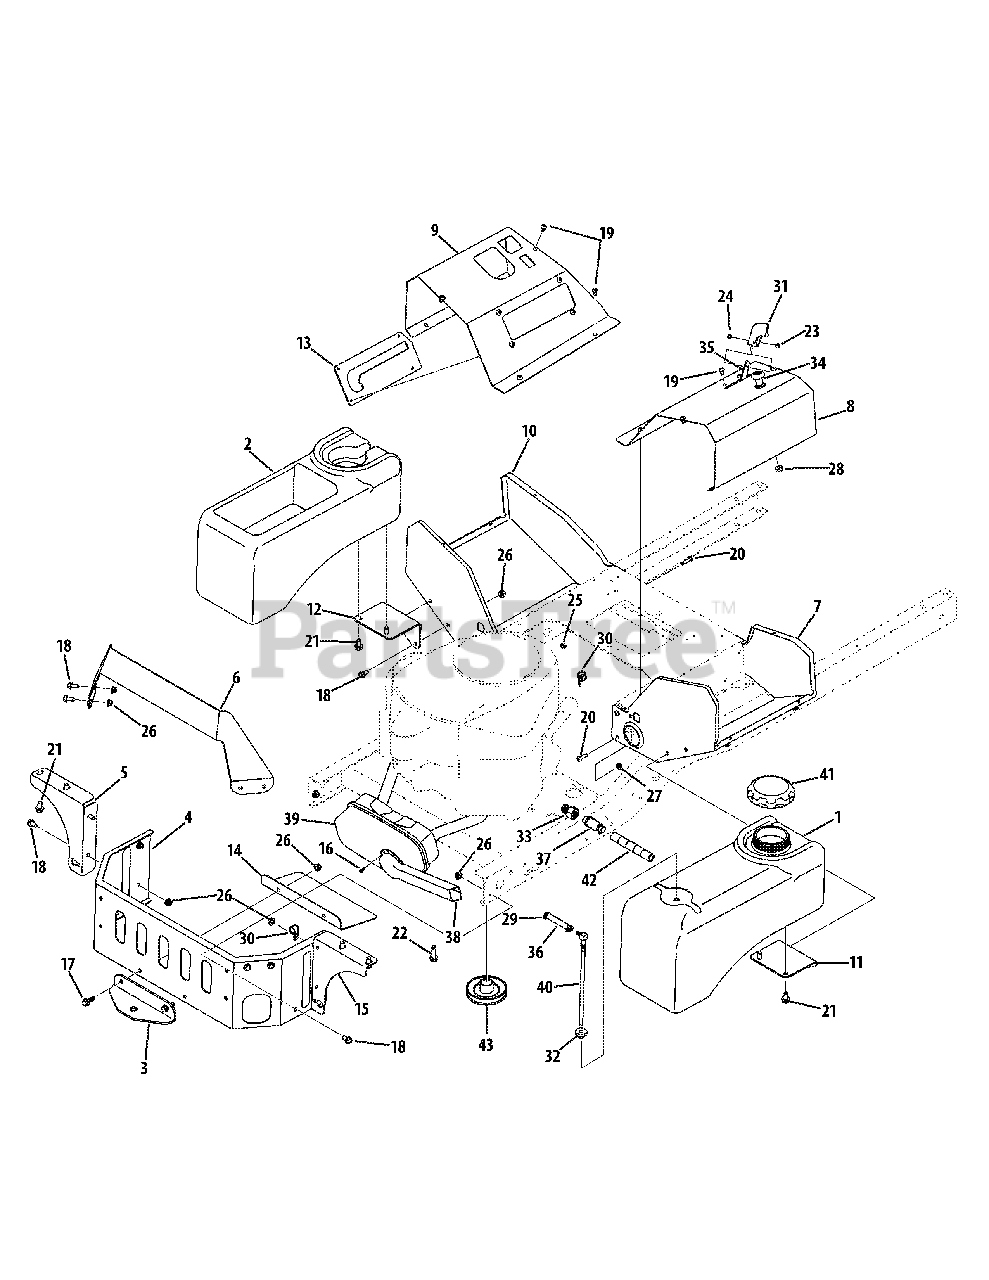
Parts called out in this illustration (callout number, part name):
1	Fuel Tank
2	Utility Bin
3	Hitch Bracket
4	Bumper Bracket
5	Tank Support Bracket
6	Upper Bumper Bracket (60" Only)
7	RH Lower Console
8	RH Upper Console
9	LH Upper Console
10	LH Lower Console
11	Right Tank Support Bracket
12	Left Tank Support Bracket
13	Parking Brake Lock Bracket
14	Muffler Mount Bracket
15	RH Fuel Tank Support Bracket
16	Hex Washer Screw, #8-18 x 0.500
17	Hex Flange, 5.16-18 x 1.0
18	Hex Washer Screw, 5.16-18 x .750
19	Screw, 1.4-20 x .5
20	Screw, 1.4-20 x 1.0
21	Hex Washer Screw, 3.8-16 x .625
22	Hex Washer Screw, 3.8-16 x 1.250
23	Machine Screw, #8-32 x0.375
24	Hex Nut, #8-32
25	Sems Nut, 1.4-20
26	Flange Lock Nut, 5.16-18
27	Flange Lock Nut, 1.4-20
28	Flange Lock Nut, 3.8-16
29	Hose Clamp, .490
30	Clamp, 9.16
31	Throttle Knob
32	Fuel Tank Bushing
33	Hex Fitting, 10 x M20
34	Choke Cable
35	Throttle Cable, 39.0 x .62
36	Fuel Hose, 1.4
37	Oil Drain
38	Long Muffler Deflector
39	Kawasaki Twin Muffler
40	Fuel Pick-Up Fitting
42	Oil Drain Extension Hose
43	Electric PTO Engine Pulley
